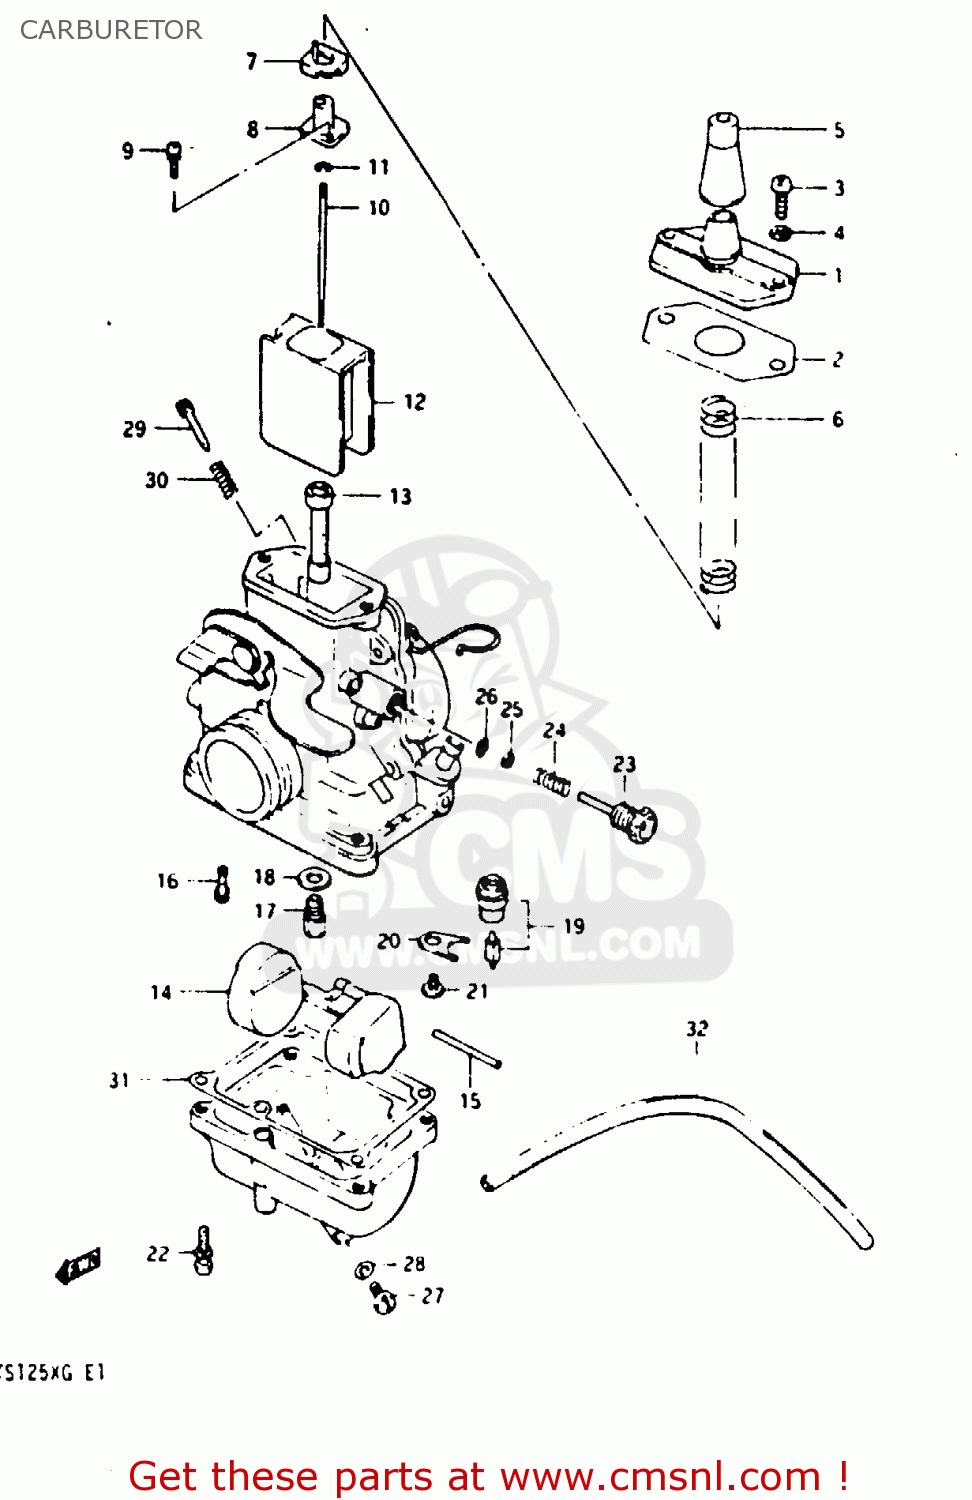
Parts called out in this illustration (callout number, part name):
1	CAP, TOP
2	GASKET,CARBURETOR TOP (NAS)
3	SCREW
4	LOCK WASHER
5	CAP,RUBBER
6	SPRING
7	RING
8	JOINT
9	SCREW
10	NEEDLE, JET (5DP1-3)
11	CLIP
12	VALVE, PISTON (CA:3.0)
13	JET,NEEDLE(0-6)
14	FLOAT
15	PIN,FLOAT
16	JET,PILOT(17.5)
17	JET
18	WASHER,NEEDLE NOZZLE
19	VALVE ASSEMBLY,NEEDLE
20	PLATE
21	SCREW 4X6
22	SCREW
23	ADJUSTER,THROTTLE STOP
24	SPRING
25	WASHER
26	O RING
27	SCREW, DRAIN
28	GASKET,DRAIN,PLUG (NAS)
29	SCREW,AIR
30	SPRING
31	GASKET,FLOAT CHAMBER (NAS)
32	HOSE
